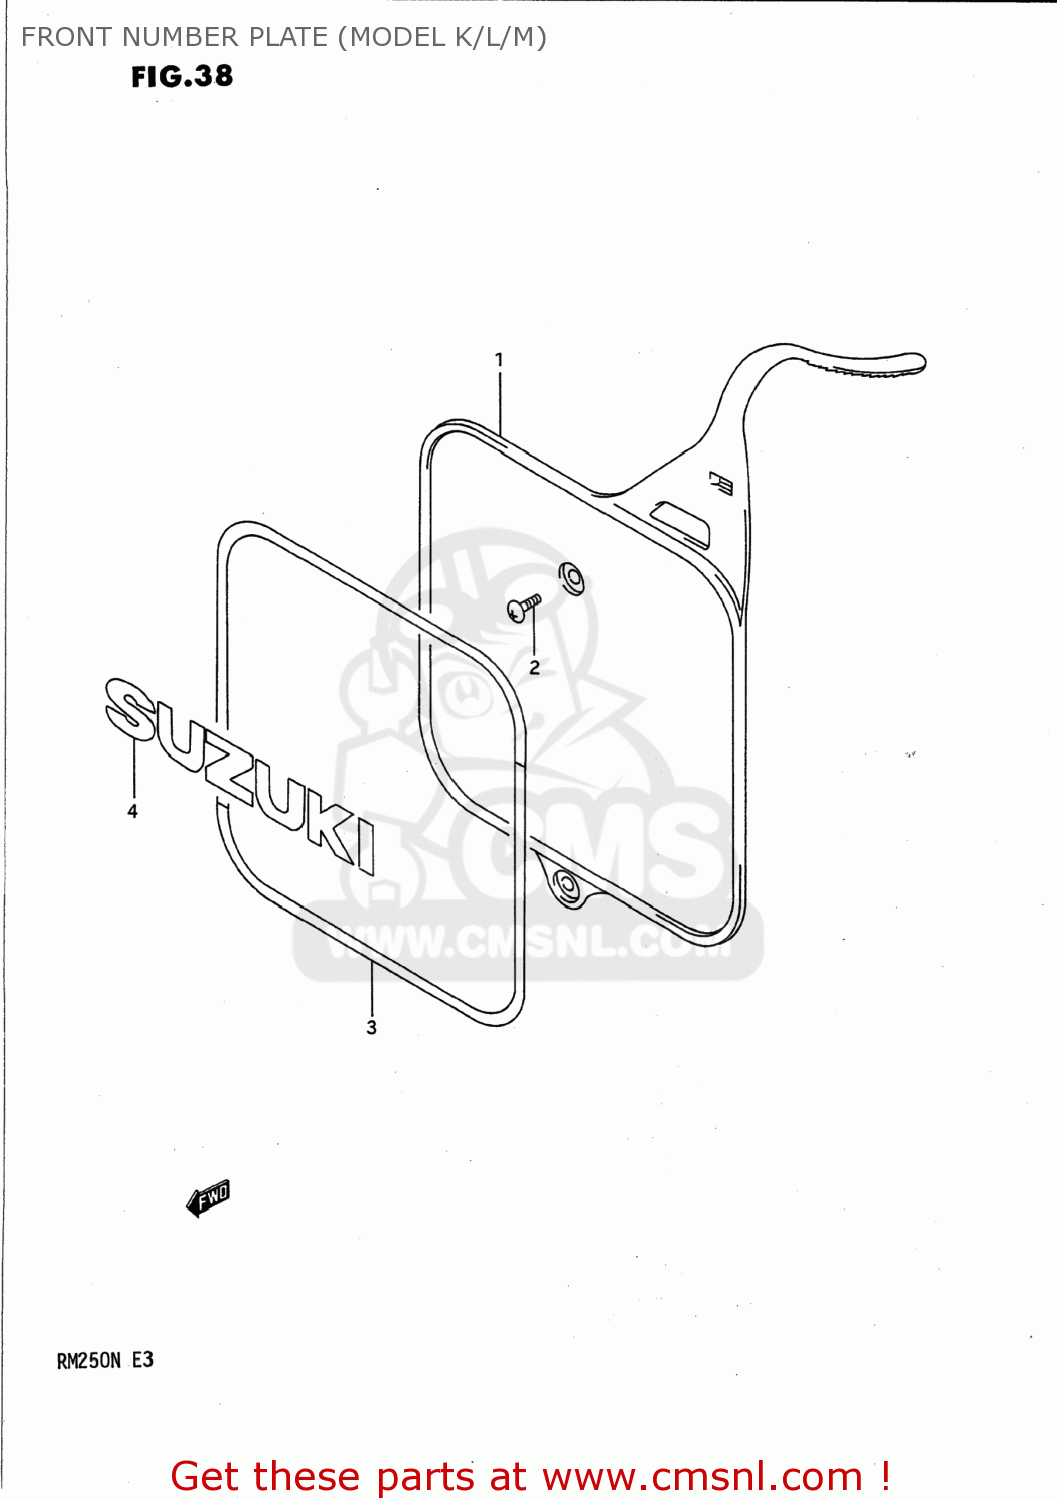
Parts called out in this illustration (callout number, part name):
1	PLATE,NUMBER,FRONT
2	SCREW
3	TAPE SET,FRONT NUMBER
4	EMBLEM,FRONT NUMBER PLATE (SUZUKI)
